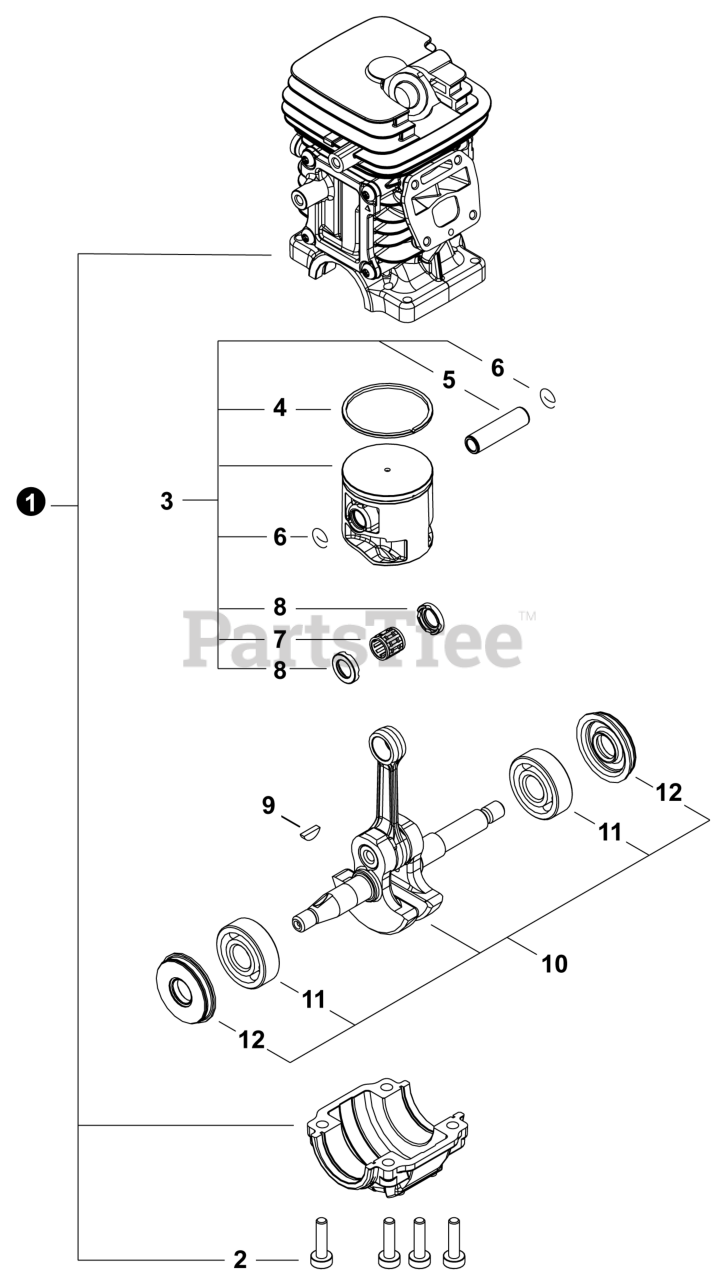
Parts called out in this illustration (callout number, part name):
1	CYLINDER ASSY
2	BOLT, TORX 5x20
3	PISTON KIT
4	RING, PISTON
5	PIN, PISTON 9
6	RING, SNAP
7	BEARING, NEEDLE 9
8	WASHER, THRUST
9	KEY, WOODRUFF
10	CRANKSHAFT ASSY
11	BEARING, BALL 6201
12	SEAL, OIL 12
